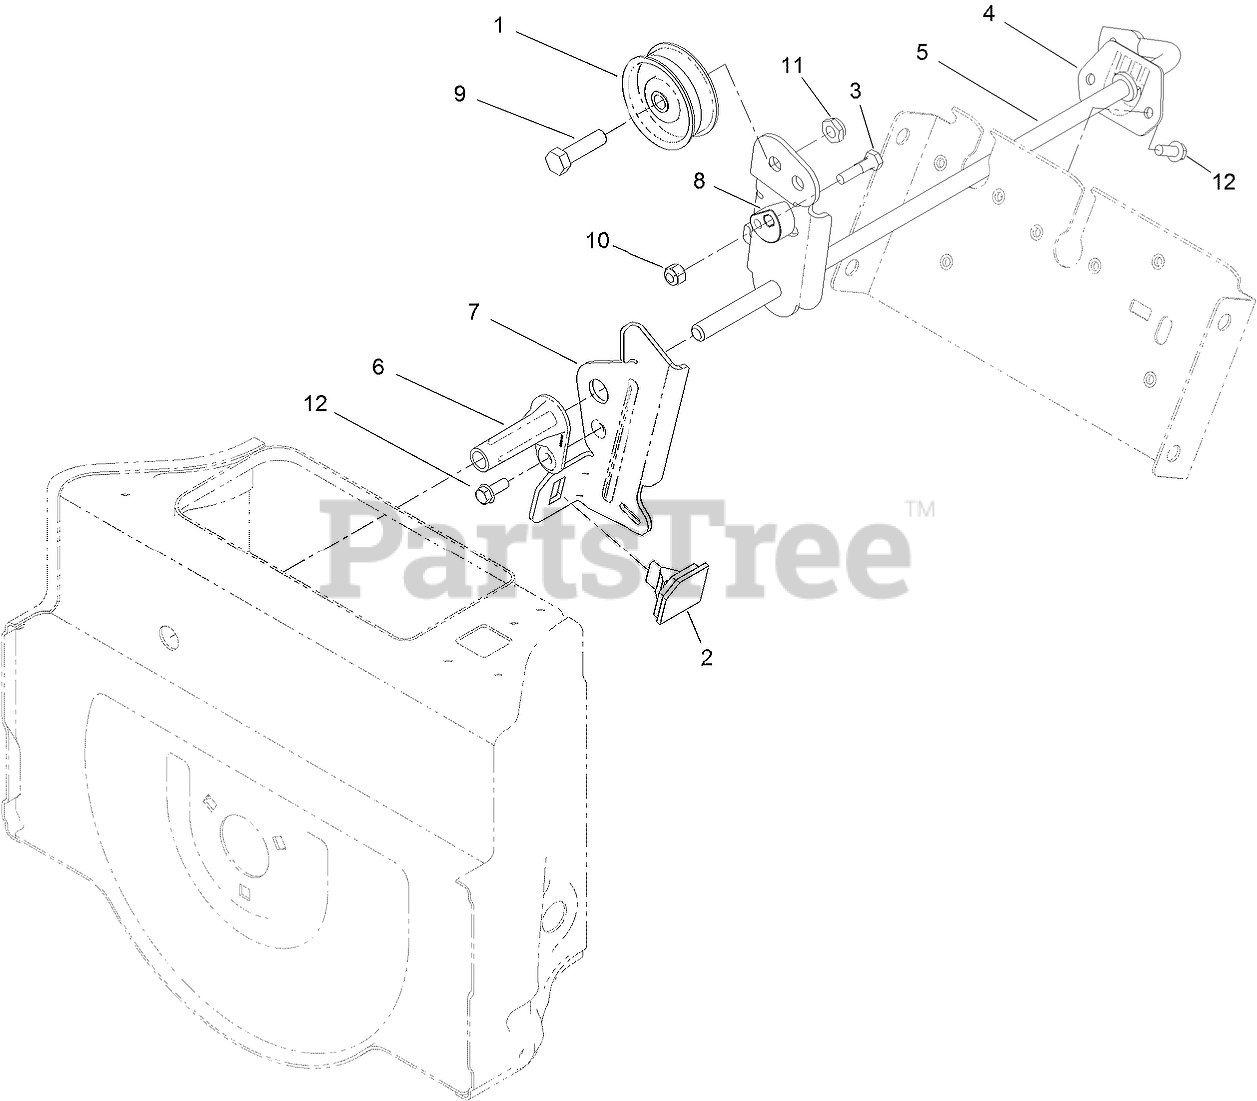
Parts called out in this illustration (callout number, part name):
1	PULLEY-IDLER
2	PAD-BRAKE
3	BOLT-PIVOT, ECCENTRIC
4	BUSHING-ROD, CLUTCH
5	IMPELLER CLUTCH ASM
6	PIVOT-BRAKE, IMPELLER
7	ARM-BRAKE, IMPELLER
8	ECCENTRIC-BRAKE, IMPELLER
9	SCREW-HH
10	NUT-LOCK, NI
12	SCREW-HWH
